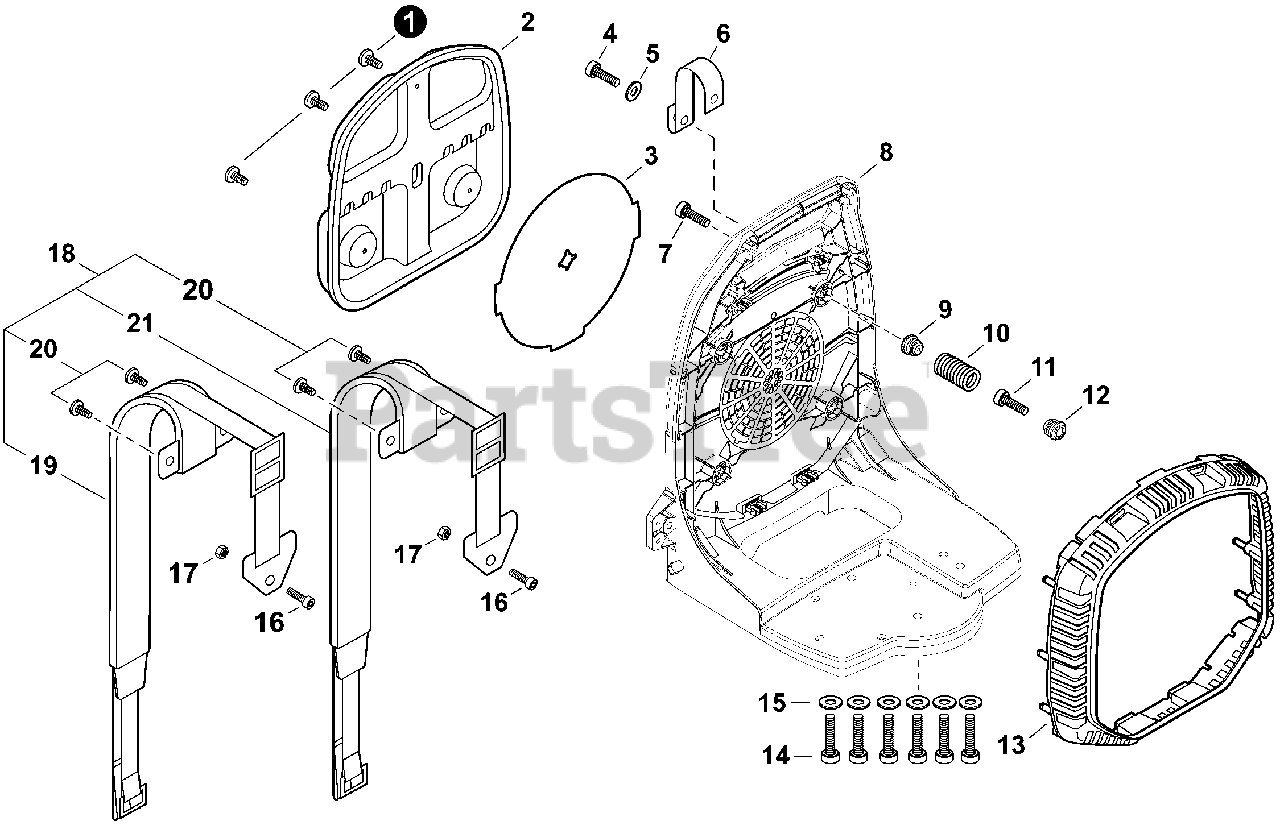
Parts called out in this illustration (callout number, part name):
2	CUSHION, BACKPACK
3	INSERT, COLD WEATHER
4	BOLT, TORX 5×20
5	WASHER 5.5×16×2T
6	STRAP, SAFETY 1.2×100
7	BOLT, TORX 5×20
8	FRAME, BACKPACK
9	HOLDER, SPRING
10	SPRING, COMPRESSION
11	BOLT, TORX 5×16
12	HOLDER, SPRING
13	GUARD, DEBRIS
14	SCREW 5×25
15	WASHER 5.5×16×2T
16	BOLT, TORX 5×30
17	NUT, LOCK M5
18	HARNESS KIT
19	HARNESS ASSY, LEFT
21	HARNESS ASSY, RIGHT
